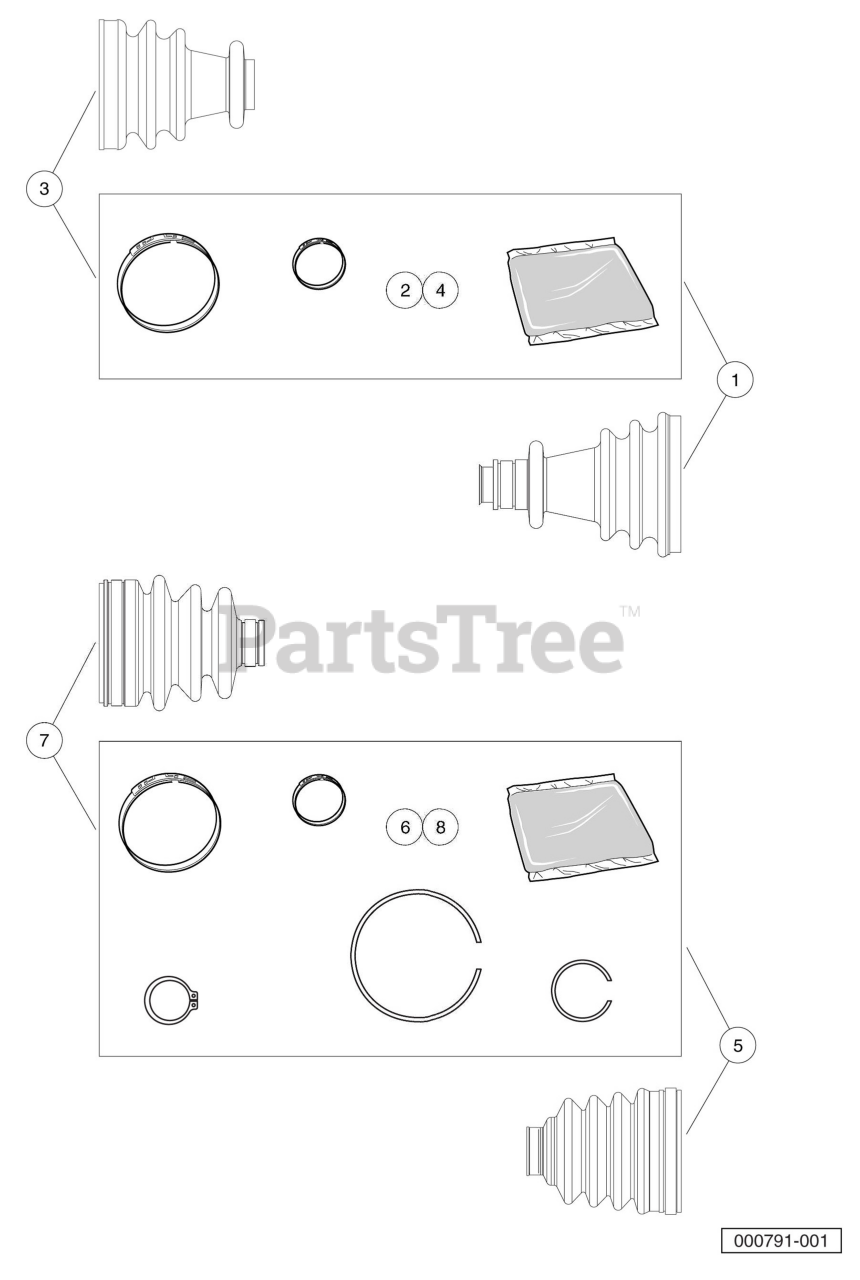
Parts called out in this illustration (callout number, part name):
1	Boxed Outboard Boot Kit
2	Half Shaft Boot Instl. Instr
3	Boxed Inboard Boot Kit
4	Half Shaft Boot Instl. Instr
5	Kit, Outer Boot, Gen 2
6	Instructions, Boot Replacement
7	Kit, Inner Boot, Gen 2
8	Instructions, Boot Replacement
